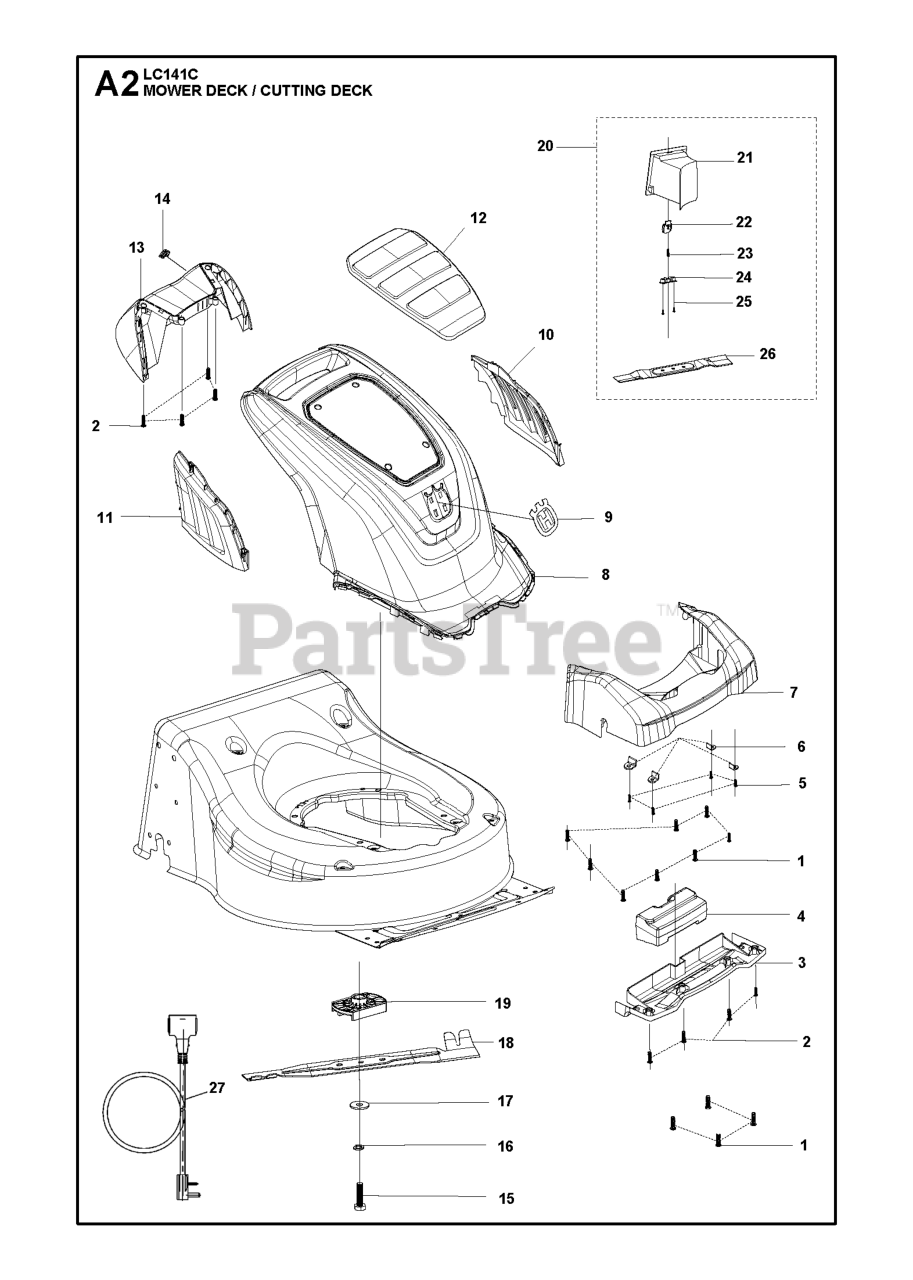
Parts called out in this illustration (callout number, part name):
3	COVER FRONT HANDLE (UNDER SIDE
4	WEIGHT # 25100184101
7	COVER FRONT COVER
9	DECAL LOGO
13	COVER BACK COVER
16	SPRING WASHER
18	MOWER BLADE MULCH 40CM PRODUCT
19	BLADE SUPPORT
21	PLUG 25232600101
26	BLADE 26300349801
